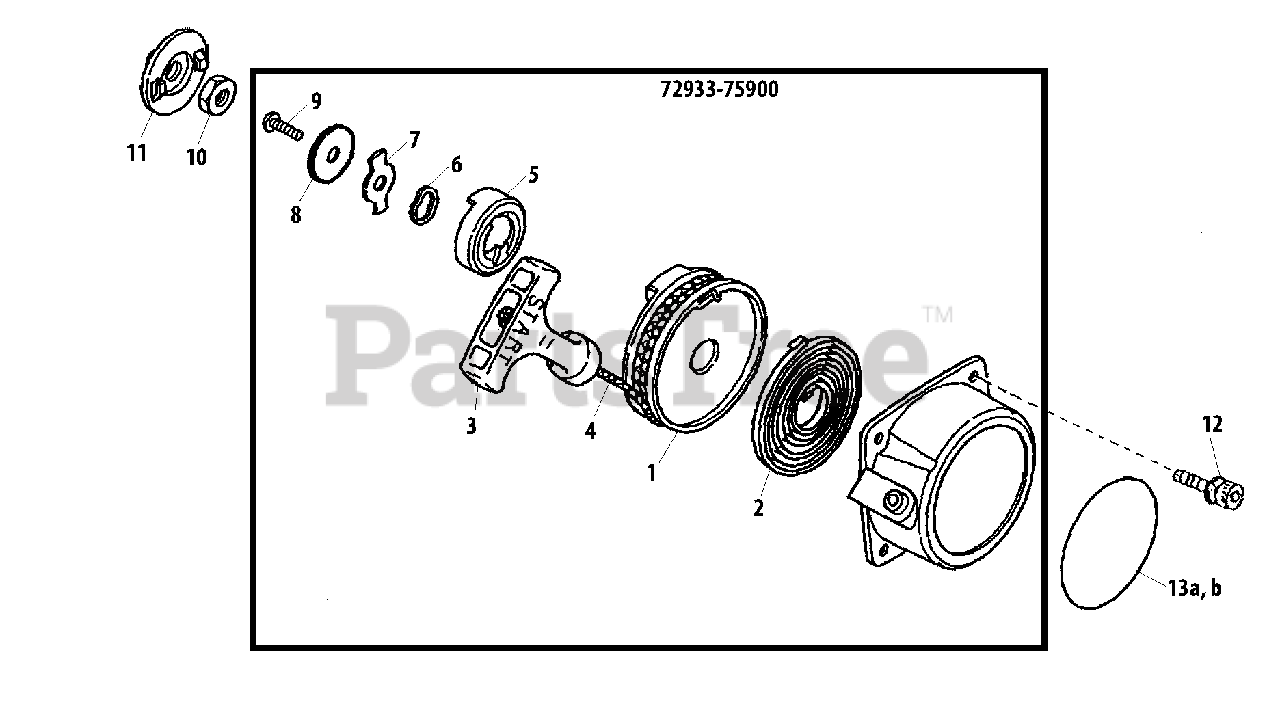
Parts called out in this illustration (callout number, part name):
1	REEL, ROPE
2	SPRING, REWIND
3	GRIP, STARTER
4	ROPE, STARTER
5	PAWL, STARTER
6	WASHER - SPRING
7	RETAINER
8	WASHER - 5
9	SCREW - 5
10	NUT - 8
11	PAWL
12	SCREW - 4X12
13A	LABEL - SHINDAIWA PROFESSIONAL
13B	LABEL
72933-75900	STARTER ASSY
